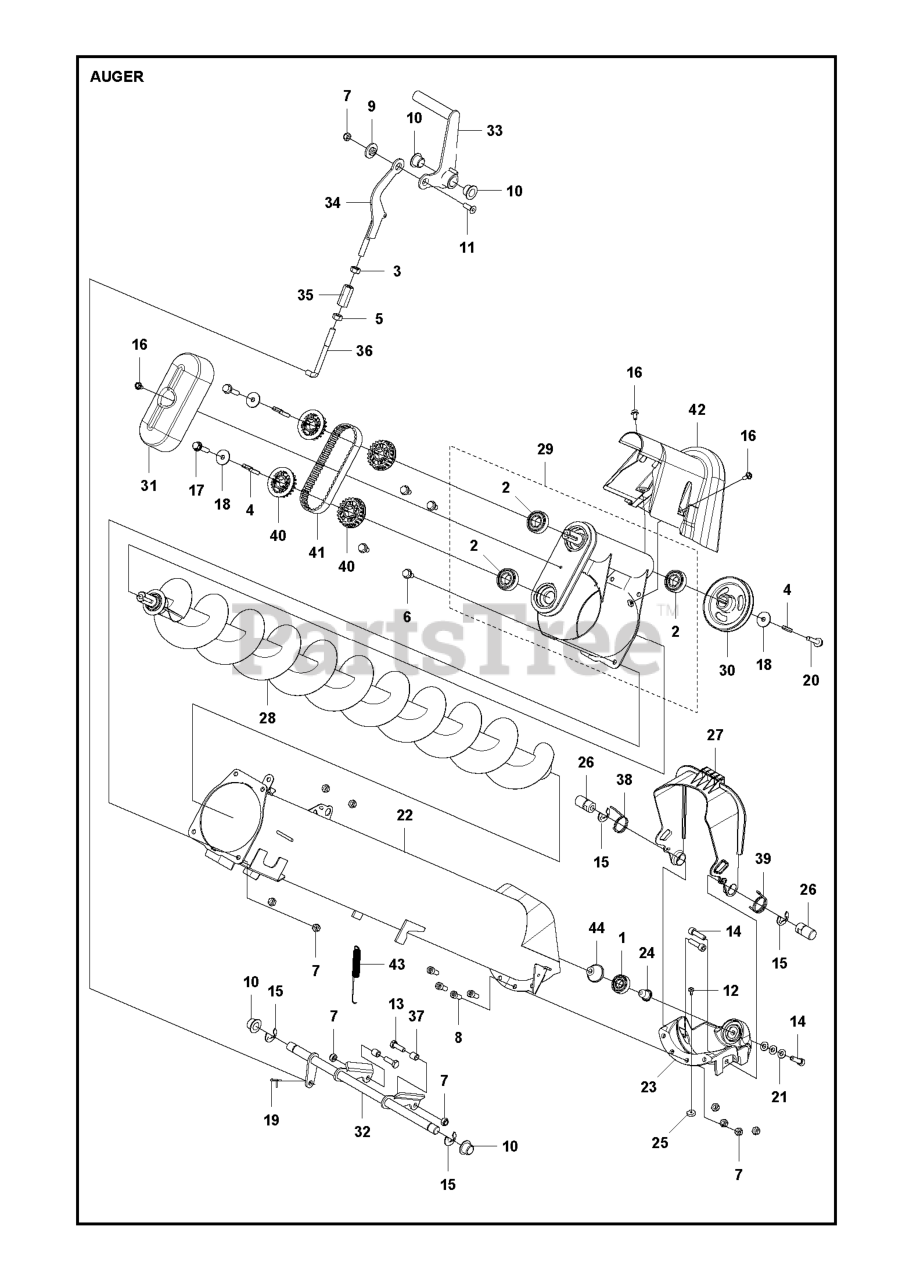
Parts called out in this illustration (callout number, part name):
1	BALL BEARING 6202-2RS1
5	NUT
7	LOCKNUT M8
9	WASHER
10	BEARING FLANGE
12	SCREW ITXPANTT M5X10 ZPB (A00
13	SCREW M6S 8X25
16	SCREW EHHFM
20	SCREW EHHFM
21	WASHER BRB 8.4X17
